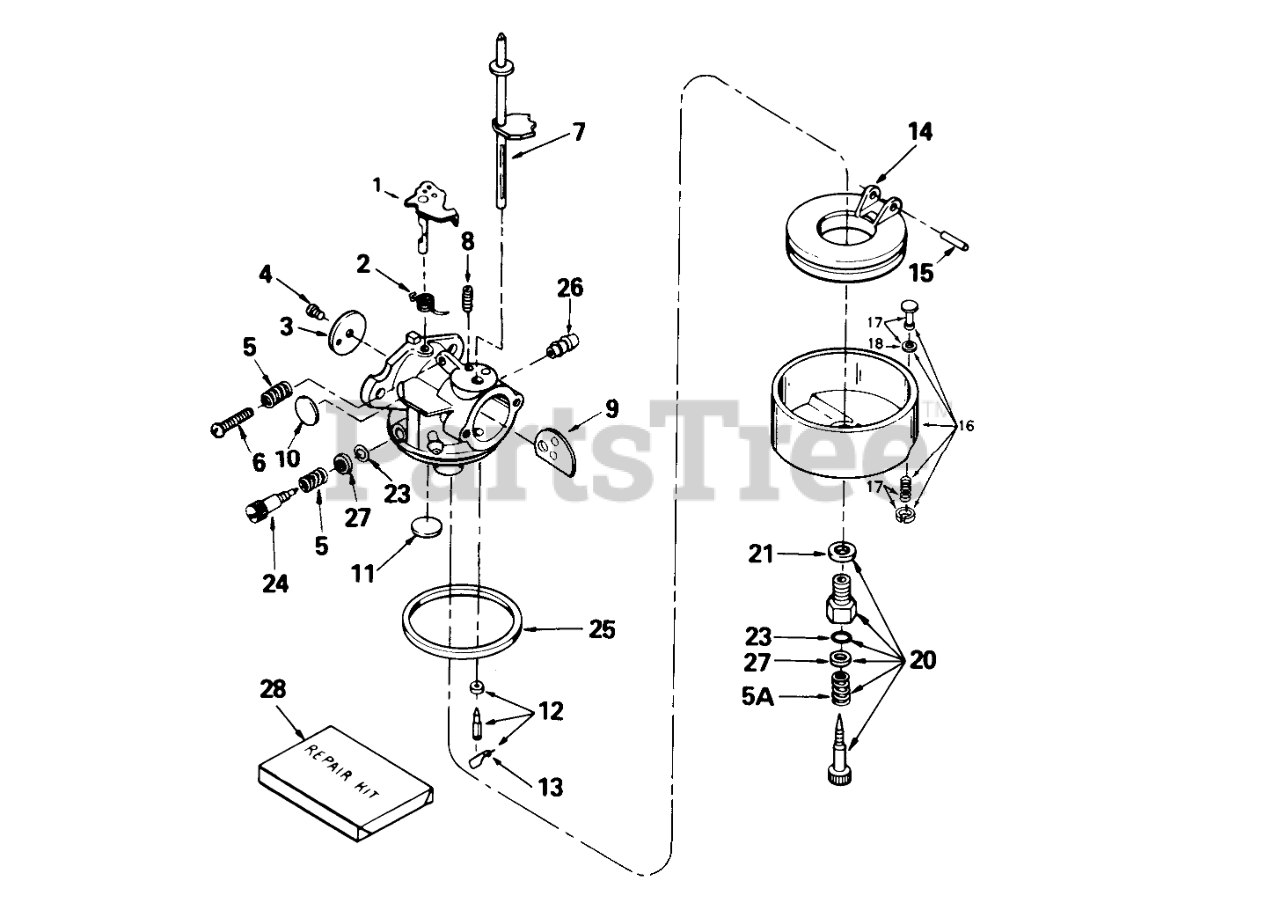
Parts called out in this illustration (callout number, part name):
1	Shaft/Lever-Throttle
2	Spring-Return, Throttle
3	Shutter-Throttle
4	Screw-Shutter
5	Spring-Tension
6	Screw-Throttle Crack Screw / Idle Speed
7	Shaft-Choke
8	Spring-Positioning, Choke
9	Shutter-Choke
10	Plug-Welch, Idle Mixture Well
11	Plug-Welch, Atmospheric Vent
12	Inlet Needle-Seat & Clip (Incl. Ref. #13)
13	Clip-Spring
14	Float
15	Shaft-Float
16	Bowl-Assembly (Incl. Ref. #17 & 18)
17	Drain Assembly-Bowl (Incl. Ref. #18)
18	Gasket-Plunger, Drain
20	Screw Adjustment Assembly (Incl. Ref. #5A, 21, 23, & 27)
21	Washer-Bowl Nut
23	"O"Ring
24	Screw-Idle
25	O Ring-Bowl, Float
26	Fitting-Fuel
28	Kit-Repair
